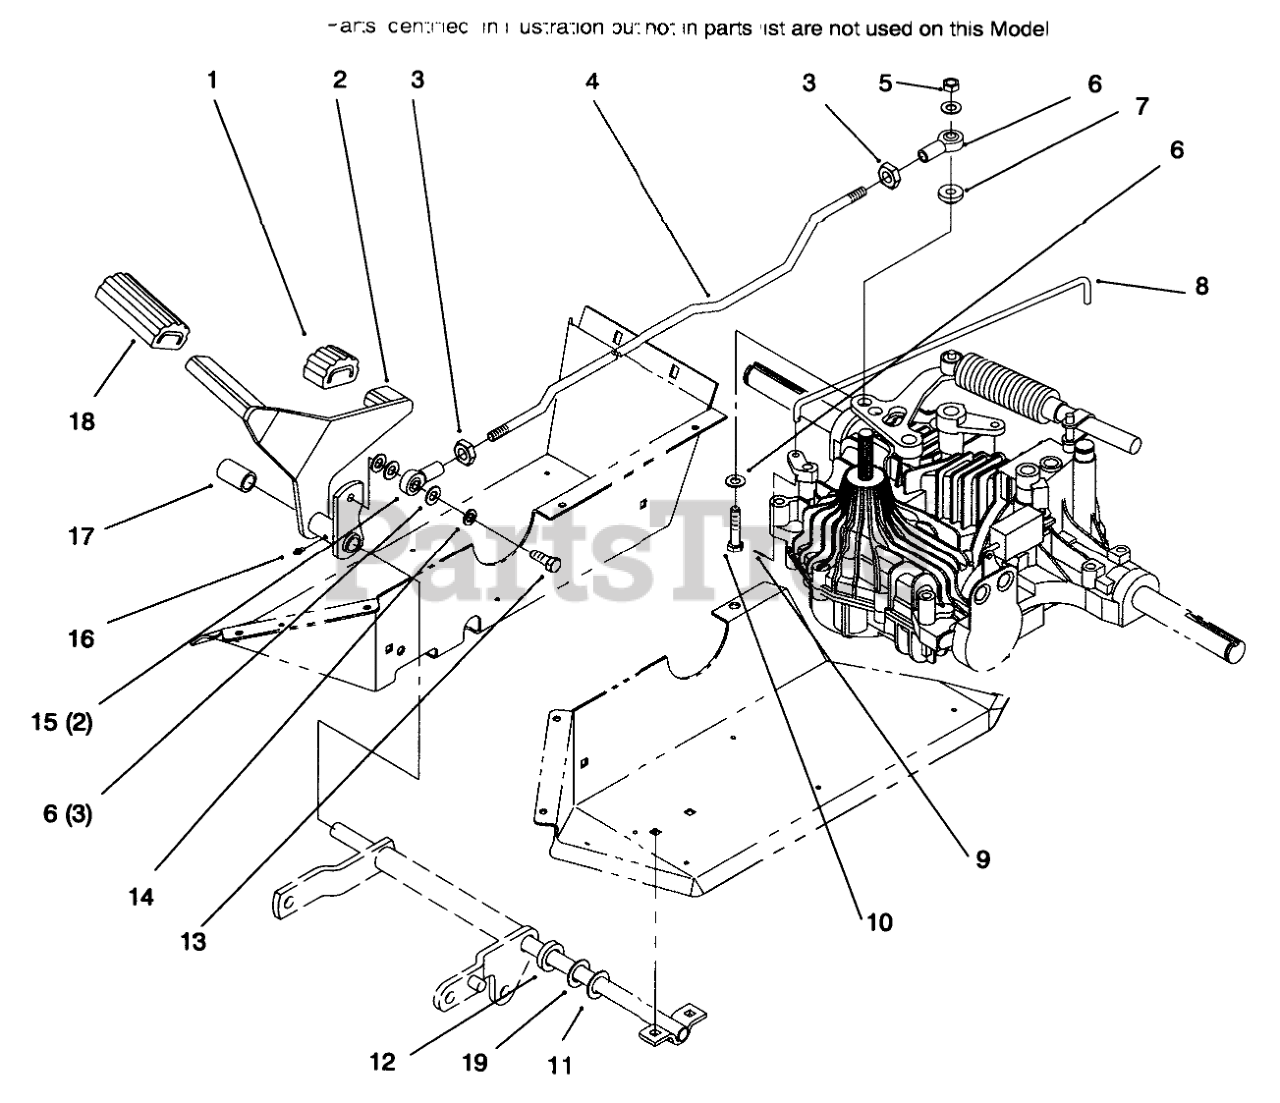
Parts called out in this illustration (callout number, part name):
1	PAD-PEDAL
2	PEDAL-HYDRO WA
3	NUT-HJ
4	ROD - HYDRO
5	NUT-LOCK, NI
6	WASHER-FLAT
7	BUSHING
8	ROD - BYPASS
9	PIN-COTTER
10	SCREW-HH
11	WASHER
12	SPACER
13	SCREW-HH
14	WASHER-LOCK
15	END-ROD, FEMALE
16	FITTING-GREASE
17	SPACER
18	PAD-PEDAL
19	WASHER-FLAT
